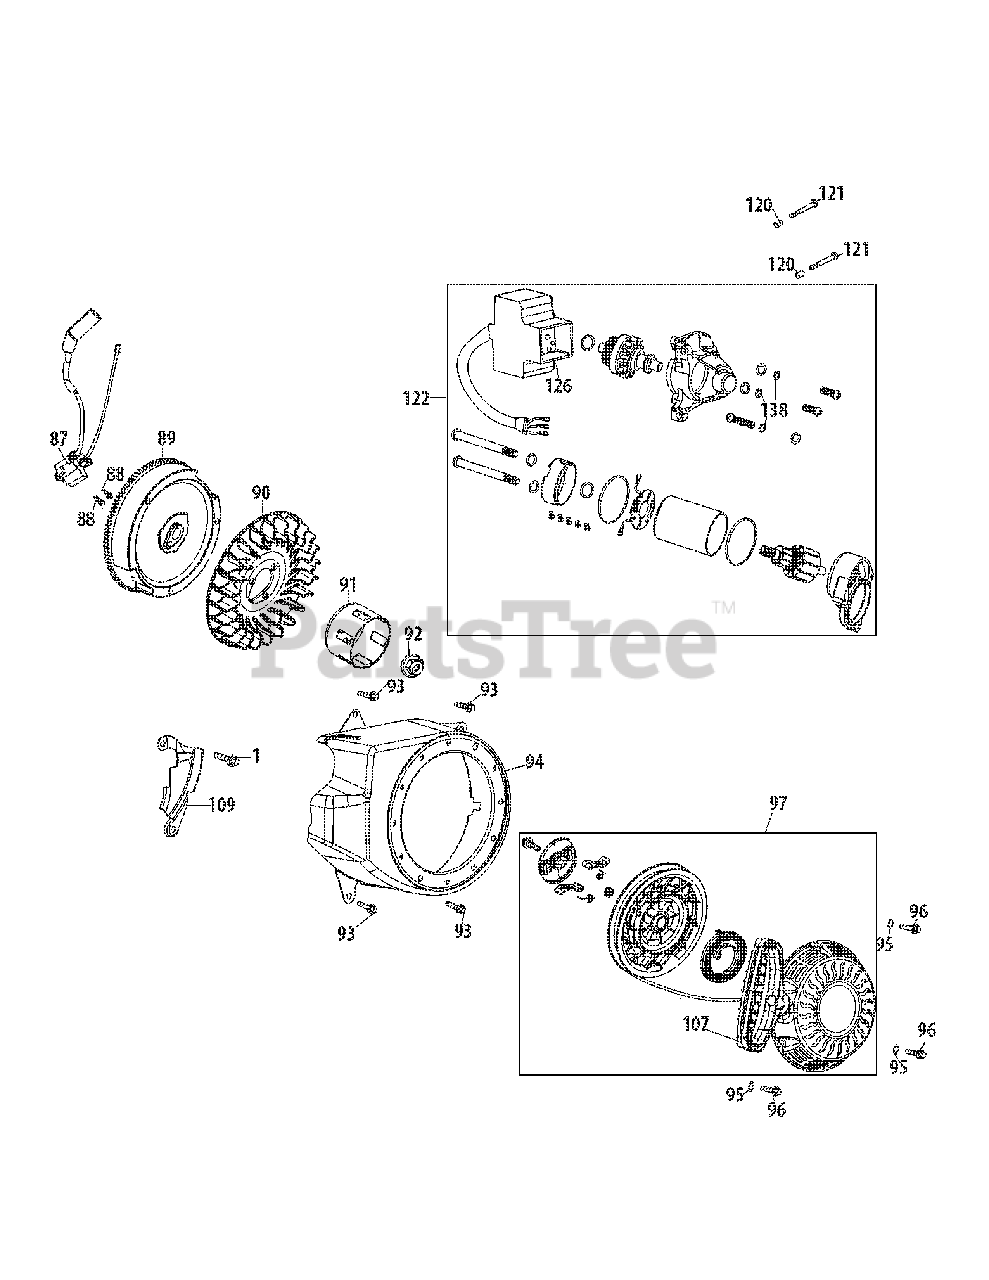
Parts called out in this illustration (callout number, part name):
1	Bolt M6×16
87	Ignition Module
88	Bolt M6×25
89	Flywheel
90	Cooling Fan
91	Starter Cup
92	Flange Nut M14×1.5
93	Bolt M6×12
94	Blower Housing
95	Washer 6
96	Bolt M6×10
97	Recoil Starter
107	Starter Handle
109	Lower Shield
120	Dowel Pin 8×8
121	Bolt M6×32
122	Electric Starter
126	Main Cable
138	Spring Washer 5
